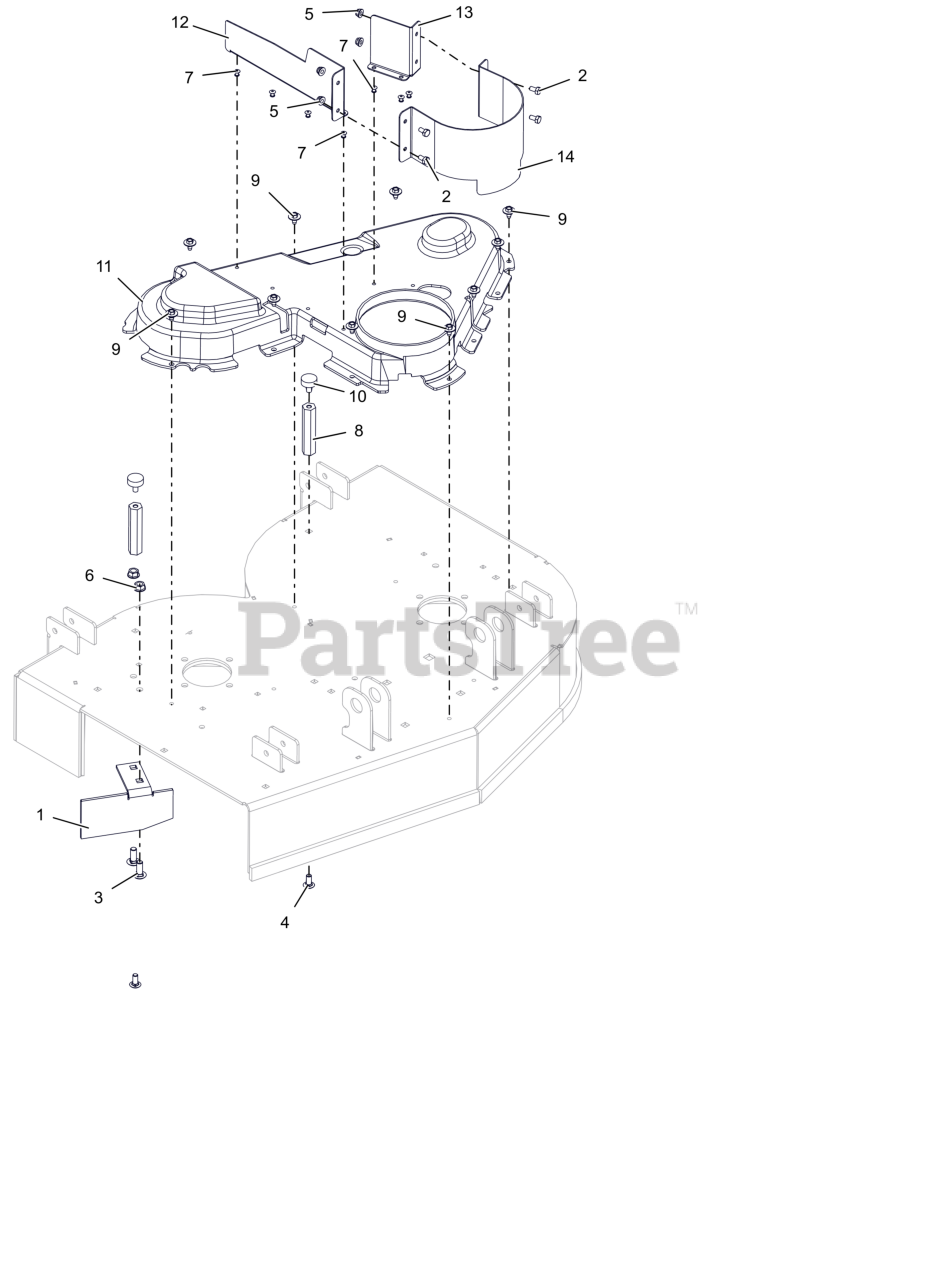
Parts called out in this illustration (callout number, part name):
1	BAFFLE, 32" SIDE DISCHARGE (ORANGE)
2	BLT,HEX .25-20X.50 G5 ZCC
3	BLT,RHSSN .38-16X1.00 G5 ZCC
4	BLT, RHSSN.31-18X.750 G5 ZCC
5	NUT,NYL-FLG .25-20 GF ZCC
6	NUT-LK-CTR-FLG .375-16 GF ZCC
7	RIVET, .1875 AL/AL .126-.250
8	NUT, .31-18 x 3.500 LG COUPLING
9	SCR, TAP .25-20X.50 LG HWH ZCC
10	BUMPER, RUBBER
11	GUARD, DECK CENTER (ORANGE)
12	GUARD, IDLER RIGHT (ORANGE)
13	GUARD, IDLER LEFT (ORANGE)
14	GUARD, IDLER FRONT (ORANGE)
